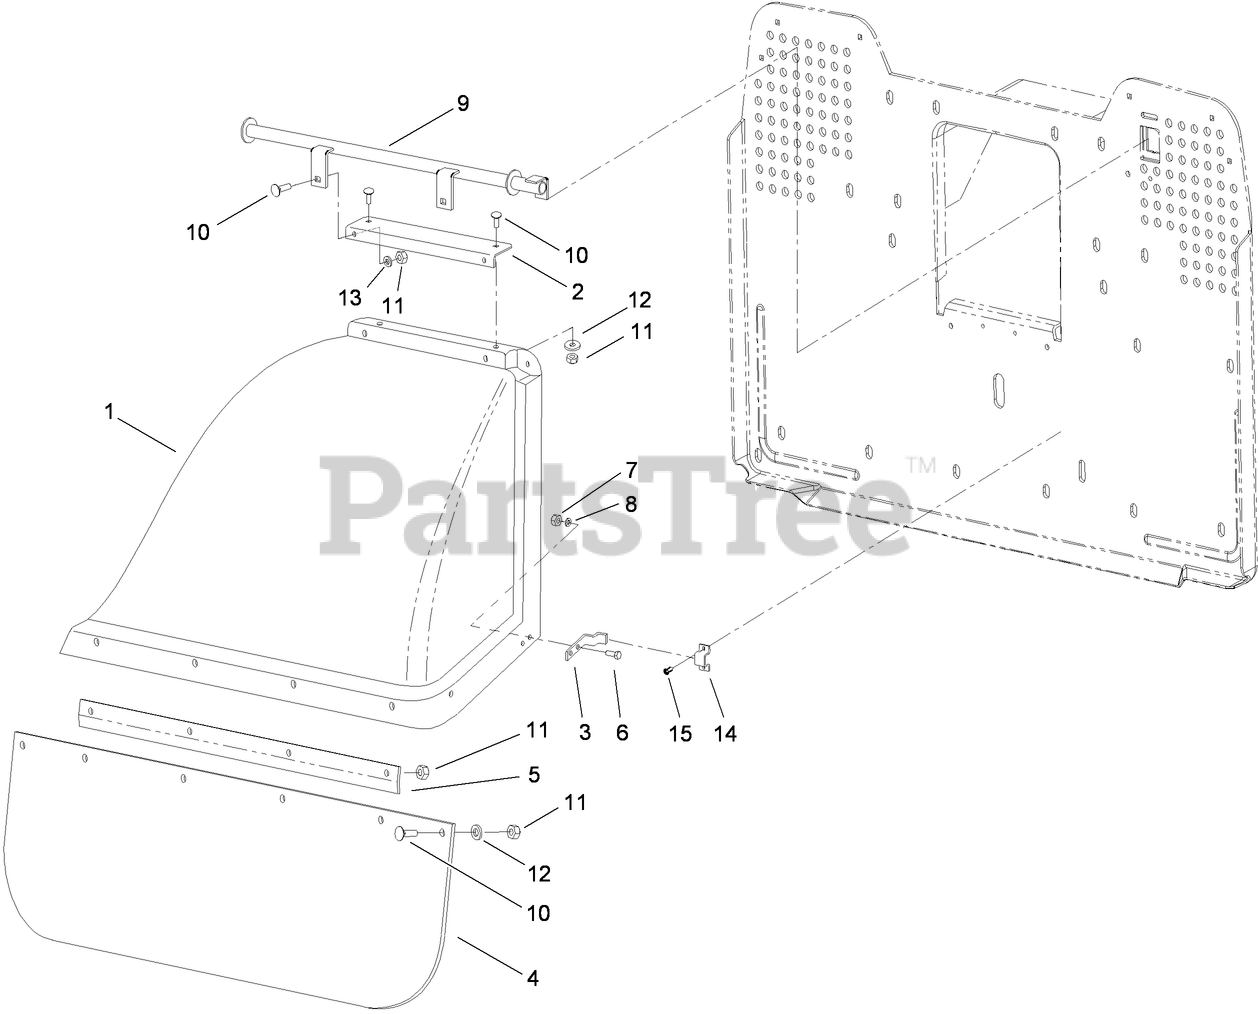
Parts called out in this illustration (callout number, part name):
1	DEFLECTOR
3	Clip-Deflector
4	SHIELD
6	SCREW-HH
7	NUT-LOCK
8	WASHER-FLAT
9	HANDLE-DEFLECTOR
10	BOLT-CARRIAGE
11	NUT-LOCK
12	WASHER-FLAT
13	WASHER
